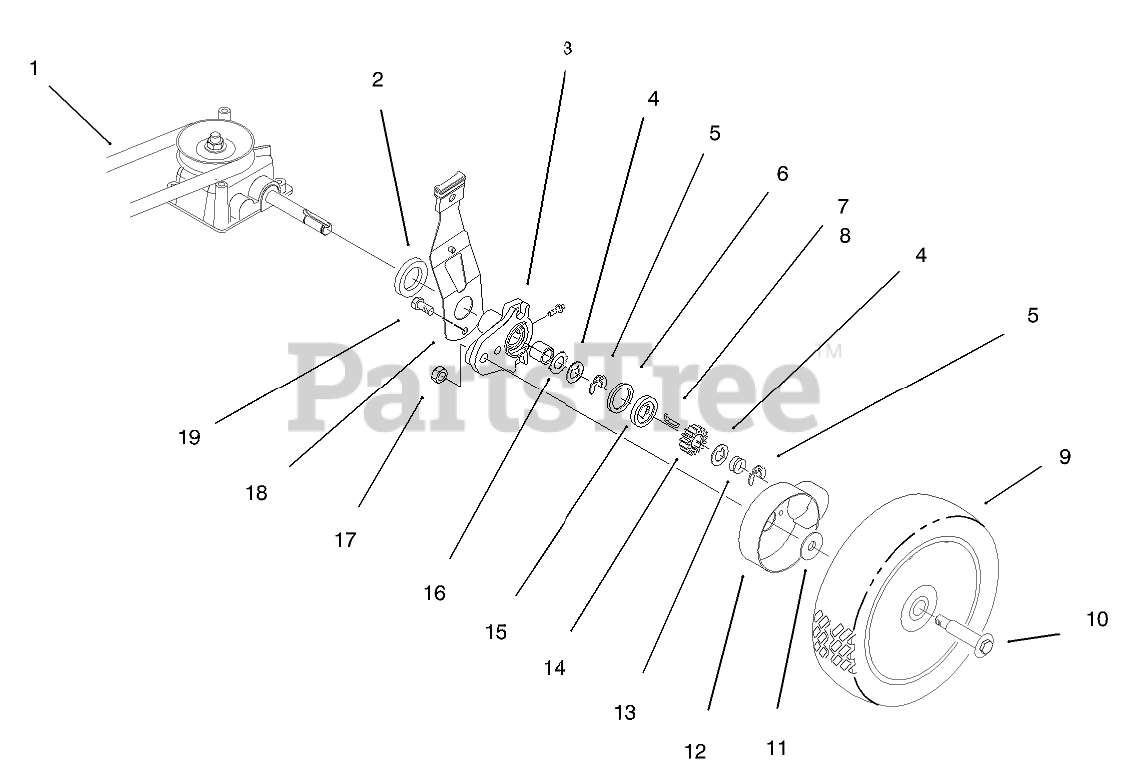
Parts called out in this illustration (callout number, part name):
1	V-BELT
2	SPACER-AXLE SHAFT
3	REAR HEIGHT ADJUSTMENT ARM ASM
4	WASHER-THRUST, KEYED
5	RING-CLIP, LOCKING
6	RING-FRICTION
7	KEY-ROCKING, RH
8	KEY-ROCKING, LH
9	WHEEL ASM
10	BOLT-SHOULDER
11	WASHER-STEPPED
12	Cover Wheel
13	SPRING-COMPRESSION
14	GEAR-PINION
15	WASHER-CLUTCH
16	WASHER-ARM, PIVOT
17	NUT-JAM, LOCKING
18	REAR SPRING ARM ASM
19	SCREW-HWH
